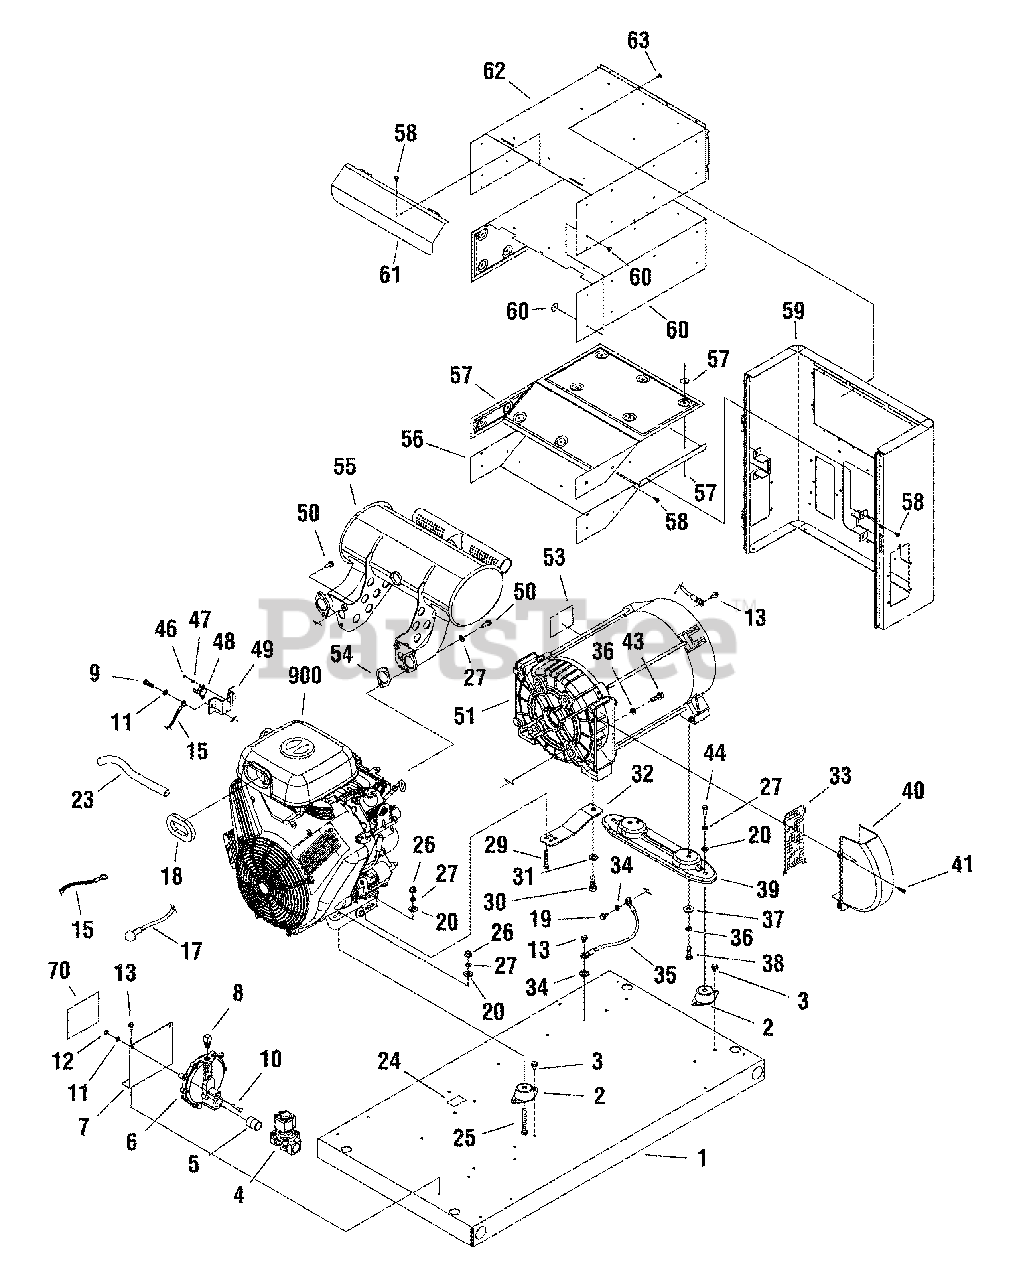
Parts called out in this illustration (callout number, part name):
2	MOUNT, Vibration
4	SOLENOID, Gas Fuel
6	REGULATOR, NG/LPG
9	* CAPSCREW, Hex Head 1 x 16
10	* CAPSCREW, Hex Head 1 x 30
11	* WASHER, 1/4 Lock
12	* NUT, M6-1.0
13	BOLT
15	CABLE, Battery, Black
17	CABLE, Battery, Red
18	TUBE
20	* WASHER, Flat 5/16 - M8
23	HOSE, Oil Drain
24	DECAL, Oil Drain
25	* CAPSCREW, Hex Head, 5/16-18 x 2.5
26	* NUT, 5/16 - 18
27	* WASHER, Lock 5/16 - M8
29	* CAPSCREW, Hex Head5/16-18 x 2" Lg.
30	* CAPSCREW, Hex Head, M12-1.75 x 35
31	* WASHER, M12
32	SUPPORT, Engine
34	* WASHER, Shakeproof, EXT, M6-1/4
36	* WASHER, 3/8 LOCK
37	* WASHER, Flat, 3/8-M10
38	* CAPSCREW, Hex Head,-3/8-16 x 1
39	SUPPORT, Alternator
43	* CAPSCREW, Square Head,3/8-16 x 1-1/4
44	* CAPSCREW, Hex Head-5/16-18 x 3/4
46	* SCREW, Phillips Head, 4-40 x 0.19
47	* WASHER, Lock#4
49	PLATE, Temp Switch
50	SCREW
51	ALTERNATOR
53	DECAL
59	BULKHEAD, Alternator
62	BOX, Muffler Top
900	** ENGINE
